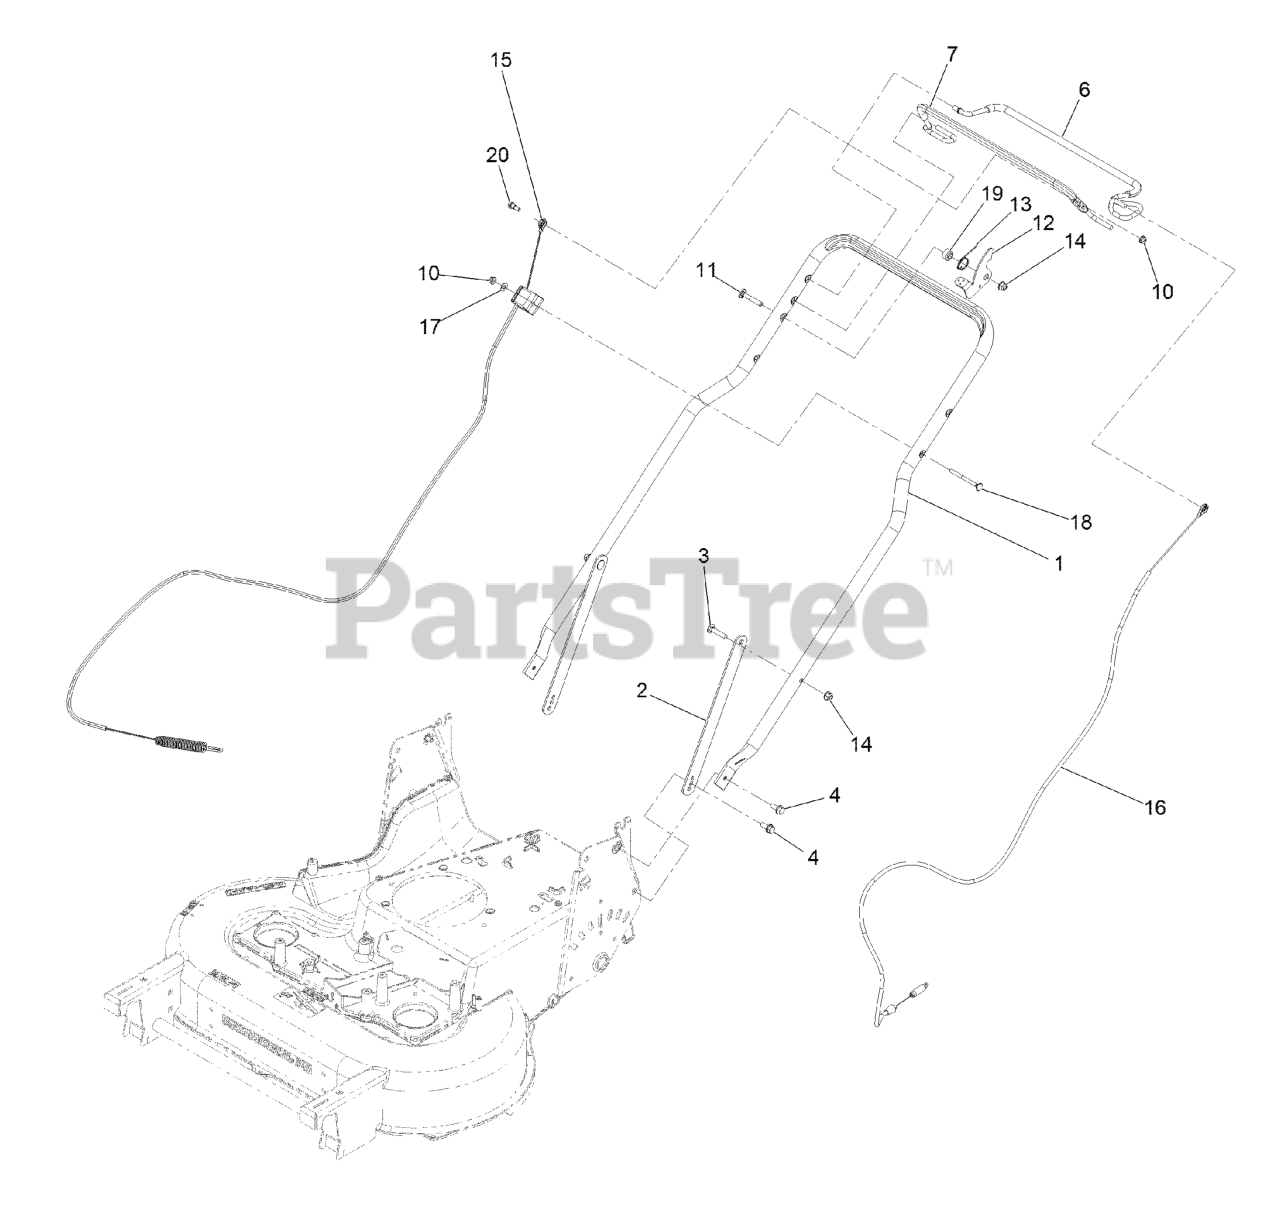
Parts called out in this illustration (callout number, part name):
2	SUPPORT-HANDLE
3	BOLT-CARR
4	SCREW-HHF
5	BUSHING-HANDLEBAR
6	BAIL-DRIVE COATED
8	BUSHING-SPRING, PIVOT
9	SPRING-RETURN, BBC
12	LEVER-BBC
13	SPRING-LEVER, BBC
14	NUT-HF, NI
15	CABLE-BRAKE, 30" 2-BAIL
16	CABLE-TRACTION
17	Washer-Flat
18	SCREW-HANDLE
19	BUSHING-STEPPED
